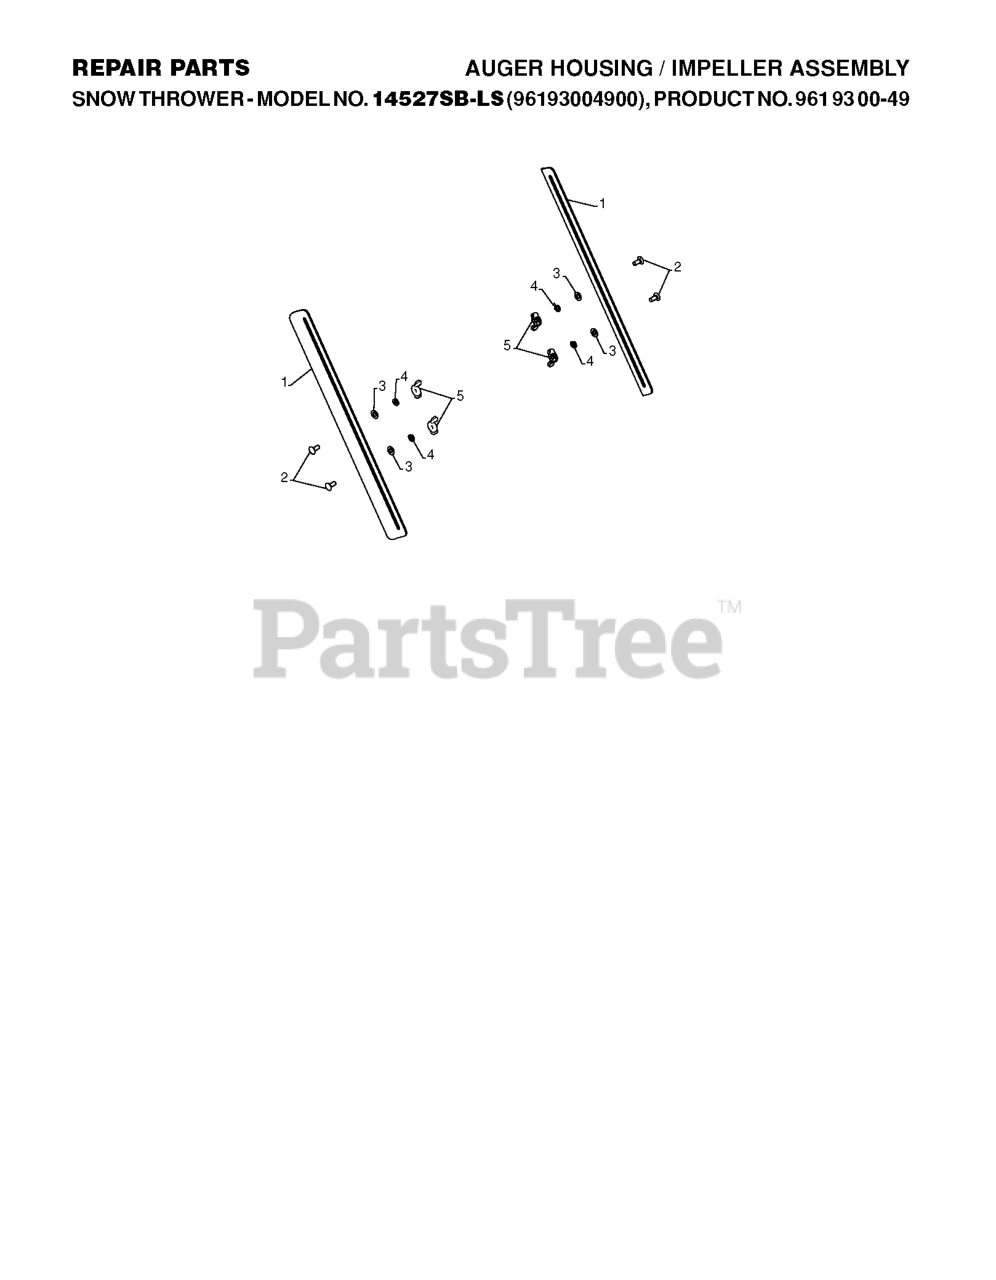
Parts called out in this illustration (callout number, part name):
1	DRIFT CUTTER BAR
2	BOLT
3	WASHER, NYLON FRICTION
4	WASHER.LOCK.HVY.HLCL.SPR.5/16
5	NUT WING PM
